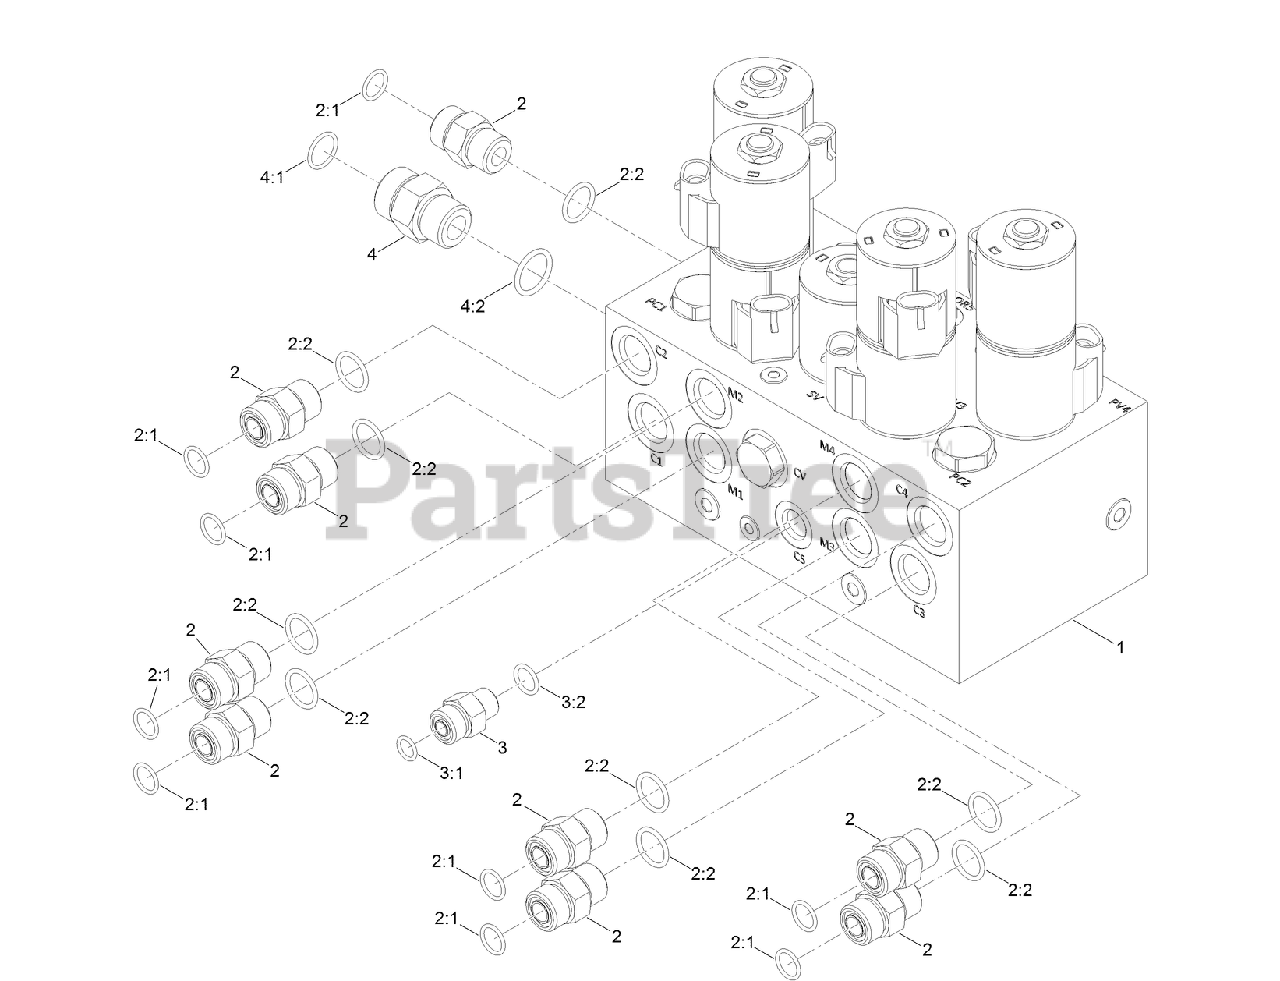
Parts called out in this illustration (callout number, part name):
1	STAKE MANIFOLD ASM
2	FITTING-STRAIGHT
2:1	O-RING
2:2	O-RING
3	FITTING-STRAIGHT
3:1	O-RING
3:2	O-RING
4	FITTING-STRAIGHT
4:1	O-RING
4:2	O-RING
